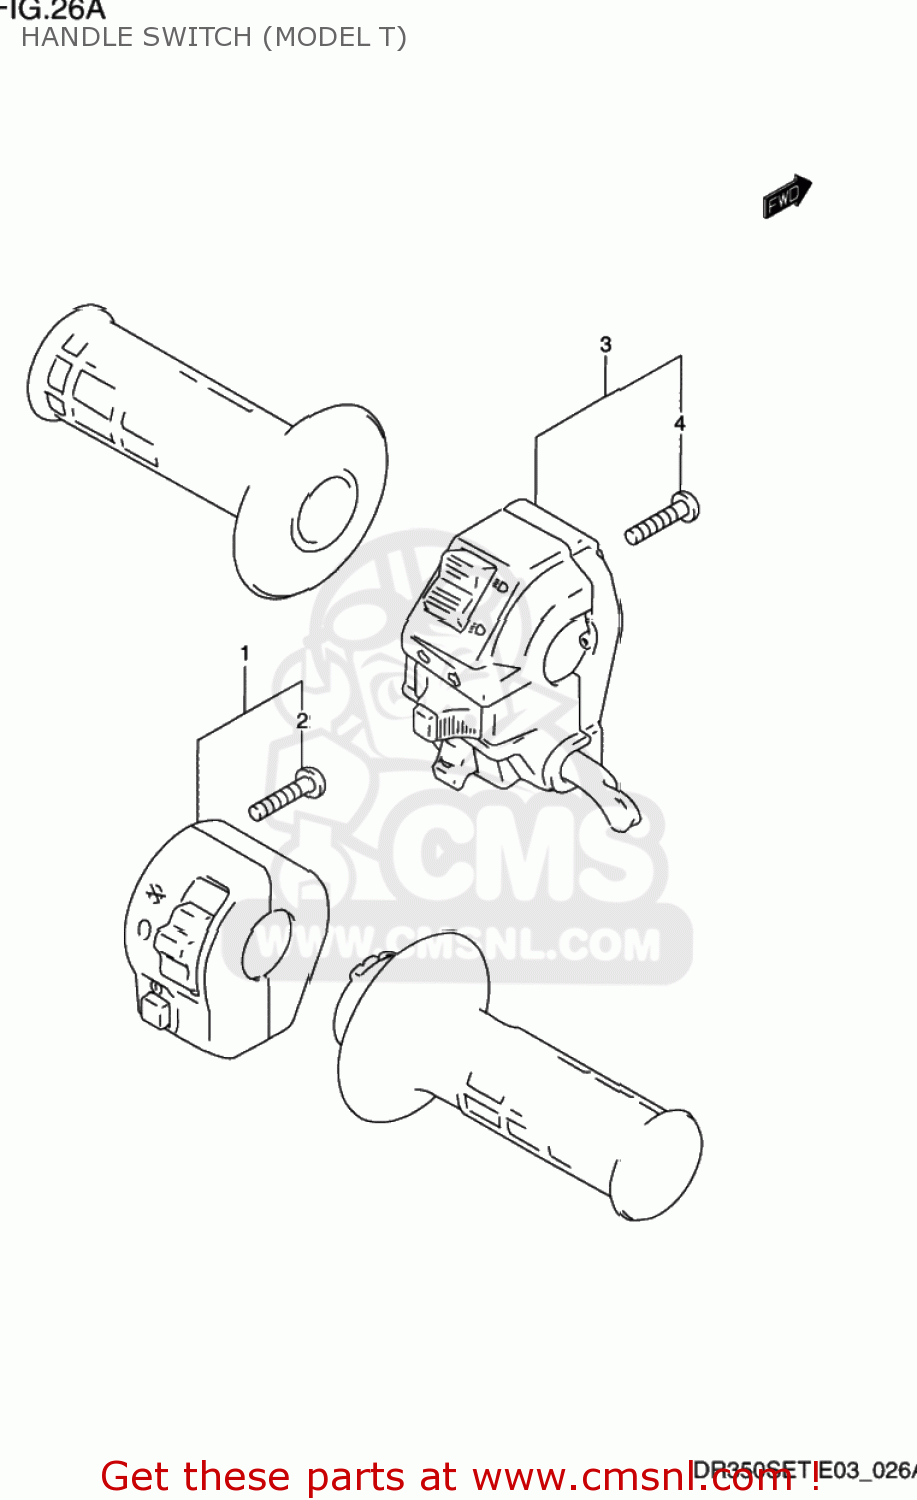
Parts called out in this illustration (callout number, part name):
1	SWITCH ASSY,HANDLE,R
2	SCREW
3	SWITCH ASSY,HANDLE,L
4	SCREW
